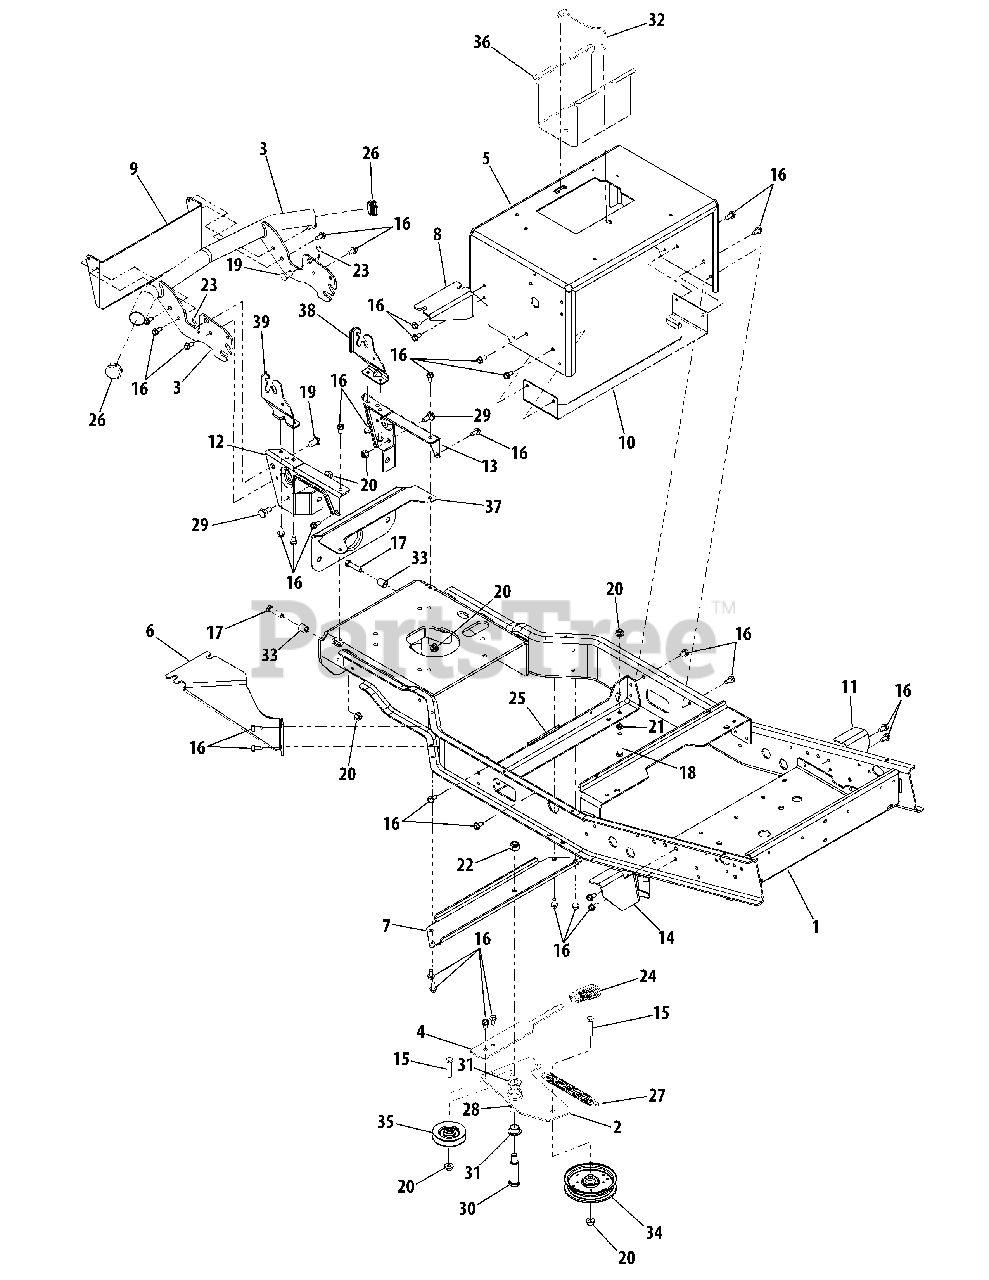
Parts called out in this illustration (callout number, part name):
16	Screw, Hex Wash. Hd. Tapp, 5/16-18 x .75
17	Hex Cap Screw, 3/8-16 x 1.5 Gr5
18	Hex Cap Screw, 3/8-16 x 2.25 Gr5
19	Pin, Clevis, .5 x .78
20	Nut, Hex Insert Flange Lock, 3/8-16 GrF
21	Nut, Hex Jam, 3/8 -16 Gr5
22	Nut, Hex Insert Lock, 1/2-13 GrB
23	Pin, Internal Cotter, .08 x 1.56
24	Grip, Handle
25	Strip, Trim
26	Cap, Bumper
27	Spring, Extension, .91 x 7.33
28	Fitting, Lube, 3/16 Drive
29	Bolt, Shoulder, .496 x .336:3/8-16
30	Screw, Shoulder, .75 x 2.23
31	Bearing, Flange, 3/4 x .52
32	Rod, Battery Hold Down
33	Spacer, . 385 x .625 x .7
34	Pulley, Idler, 4.25" Dia.
35	Pulley, V-Idler, 3.06" Dia
